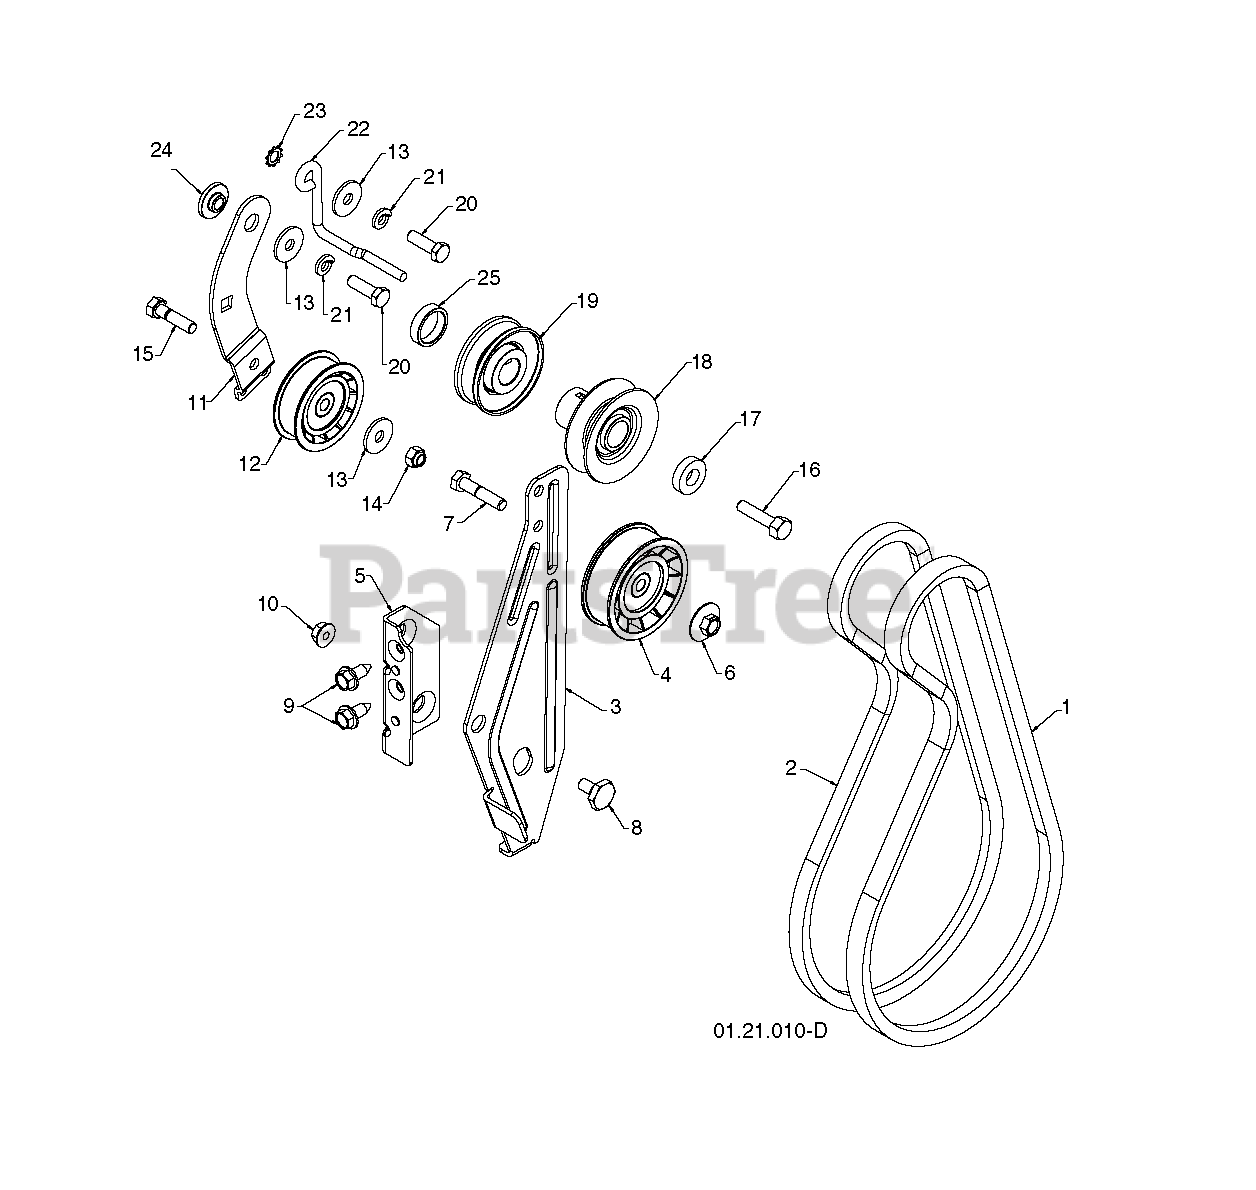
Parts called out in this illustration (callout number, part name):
1	BELT.V.IMPELLER
2	V-BELT.TRACTION.HYDRO
3	ARM.IDLER.BRAKE.
4	PULLEY.W/SPACER.2.75
5	RP BRACKET.IDLER.PIVOT
6	NUT.FLANGE.HEX.5/16X18.BLACK
7	HEX BOLT
8	BOLT.SHOULDER.1/2X12
9	BOLT.5/16HEX.WHS.HD
10	NUT.LOCK.5/16-18
11	ARM, IDLER
12	PULLEY.W/SPACER.2.75
13	STEEL WASHER
14	NUT.71038.31-18.HEX.NYLOCK
15	BOLT.5/16-18X1-1/4 FULL.THREAD
16	SCREW, HEX HD 3/8-24 X 1-3/8
17	WASHER, FLAT 3/8
18	PULLEY.IMPELER.
19	PULLEY,ENGINE TRACTION DRIVE
20	CAPSCREW.HEXHD.5/16X1.25.
21	LOCKWASHER
22	GUIDE.BELT.HYDRO.LS.SNOW
23	WASHER.20X8.5
24	RP BUSHING, IDLER PIVOT
25	SPACER.ENGINE.PULLEY
